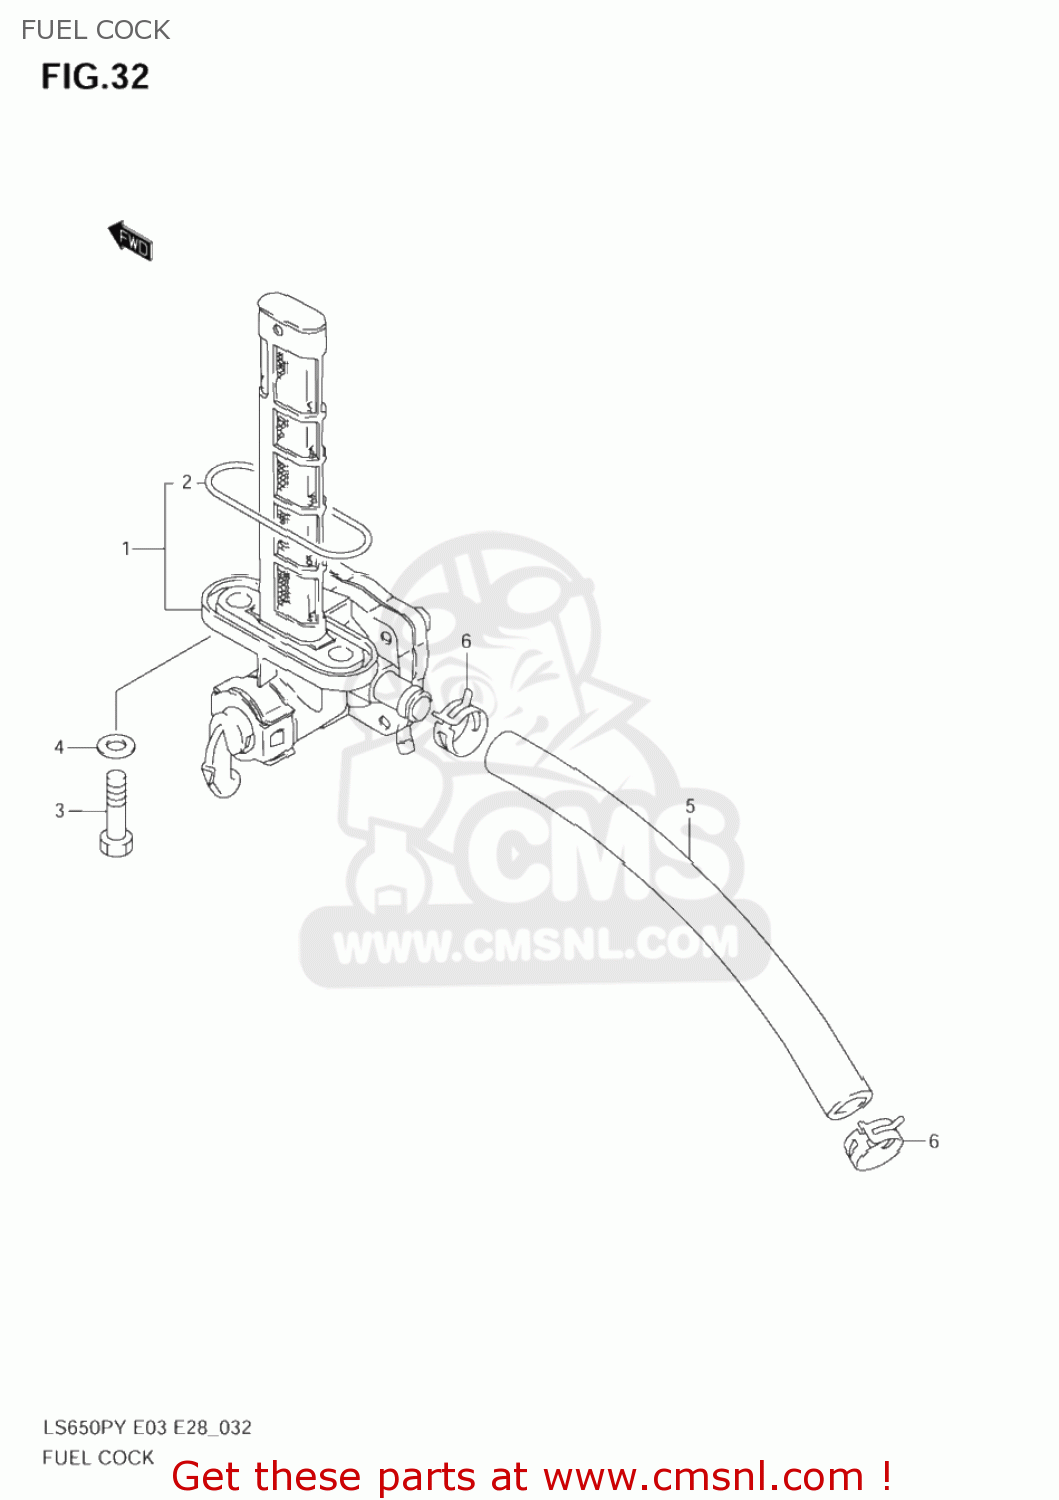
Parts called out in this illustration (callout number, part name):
1	COCK ASSY,FUEL
2	O RING,FUEL COCK
3	BOLT(6X20)
4	GASKET(6.4X11.5X0.8) (NAS)
5	HOSE(7X12X600)
6	CLIP
